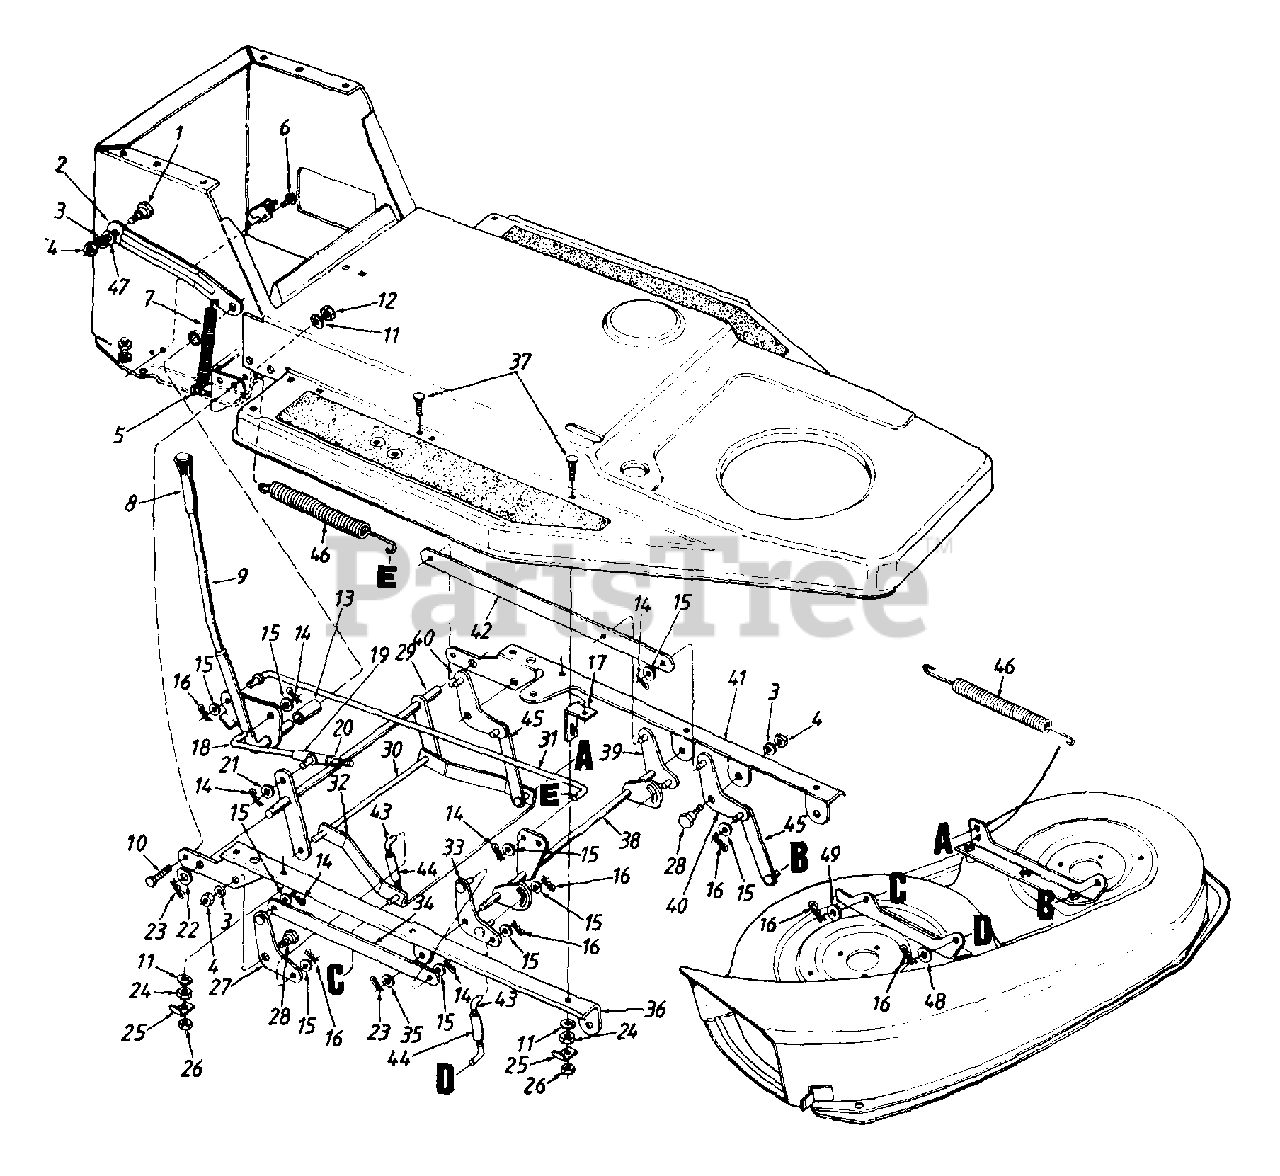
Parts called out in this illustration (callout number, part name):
1	Shld. Bolt .5" Dia. x .34" Lg.
4	Hex Nut 3/8-16 Thd.
5	Hex Bolt 1/4-28 x 1.25" Lg.
6	Hex Wash. Hd. TT-Tap Scr. 1/4-20 x .5" Lg.
9	Deck Lift Handle Ass'y.
10	Hex Wash. TT-Tap Scr. 5/16-18 x .62" Lg.
11	L-Wash. 5/16" I.D.
12	Hex Nut 5/16-18 Thd.
13	Spacer 5/8" I.D. x .78"
14	Cot-Pin 3/32" Dia. x .75" Lg.
15	Fl-Wash. .406" I.D. x .75" O.D.
16	Internal Cot-Pin 5/16" Dia.
19	Pivot Sleeve Ass'y.
20	Hex L-Nut 3/8-16 Thd.
21	Thrust Washer .382" I.D.
22	Fl-Wash. .635" I.D. x .93" O.D.
23	Cot-Pin 1/8 Dia. x 1.25" Lg.
24	Hex Nut 5/16-24 Thd.
25	Harness Retainer
26	Hex Cent. L-Nut 5/16-24 Thd.
27	Deck Pivot Brkt. Ass'y. - R.H. Rear
28	Shld. Bolt .625" Dia. x .170" Lg.
31	Deck Lift Rod
32	Deck Stabilizer Brkt.
44	Adj. Lift Link Ass'y.
45	Deck Lift Link Ass'y.
46	Deck Spring 10.33" Lg.
47	Fl-Wash. .531" I.D. x .94"
48	Fl-Wash. .406" I.D. x .75"
49	Fl-Wash. 3/8" I.D. x 1" O.D.
